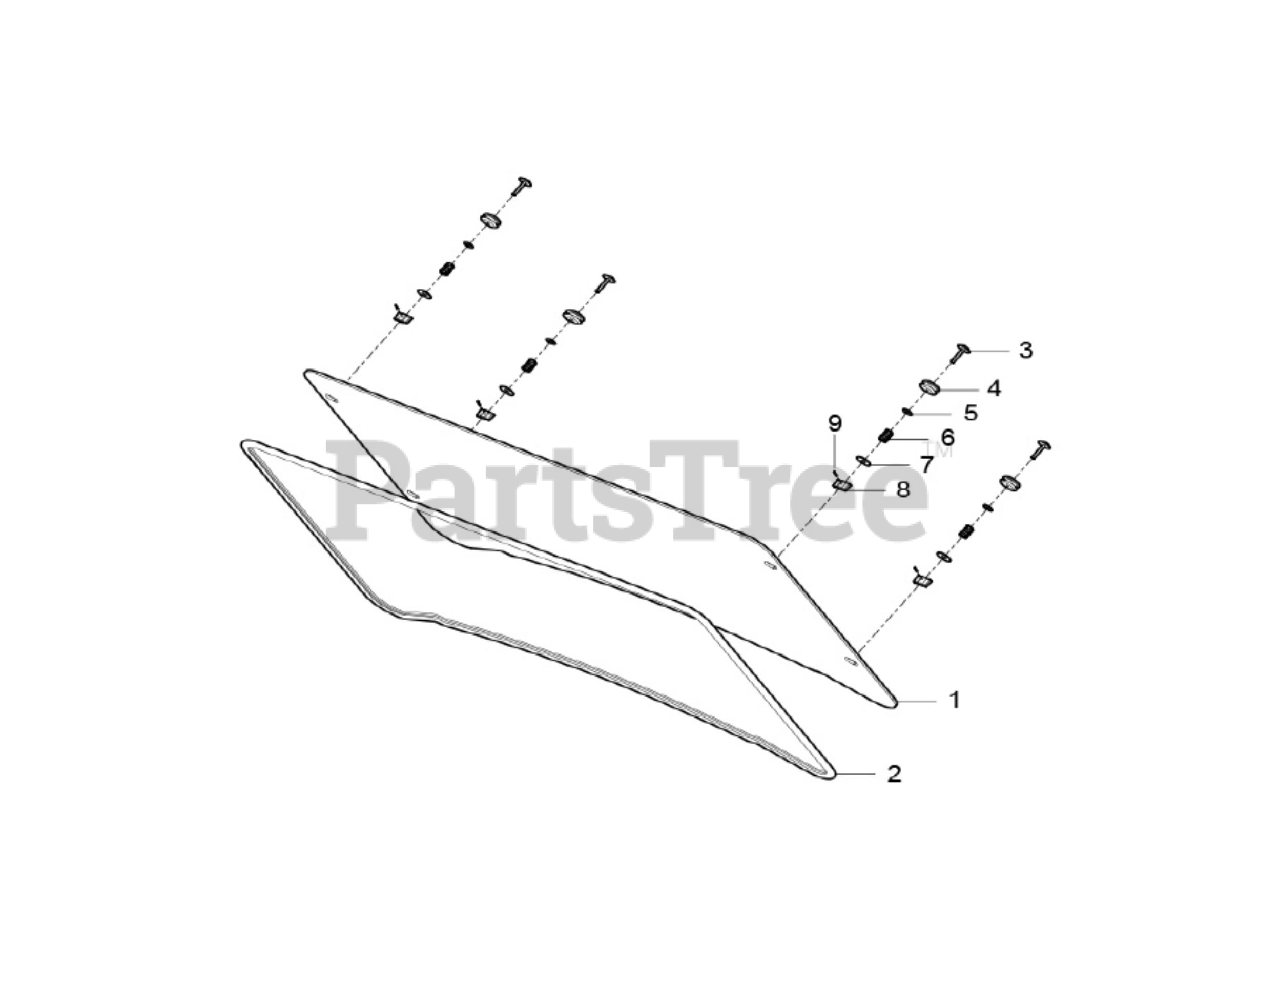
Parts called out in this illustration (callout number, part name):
1	FRONT WINDSHIELD ASSEMBLY
2	WINDSHIELD SEAL
3	LOCK PIN - WINDSHIELD
4	RUBBER WASHER 6 X 6.4
6	PRESSURE SPRING N
7	MIDDLE SHAFT ASSEMBLY , FRONT DIFFERENTIAL
8	HAND SHANK LOCK
9	PIN SPRING 3.4X10
